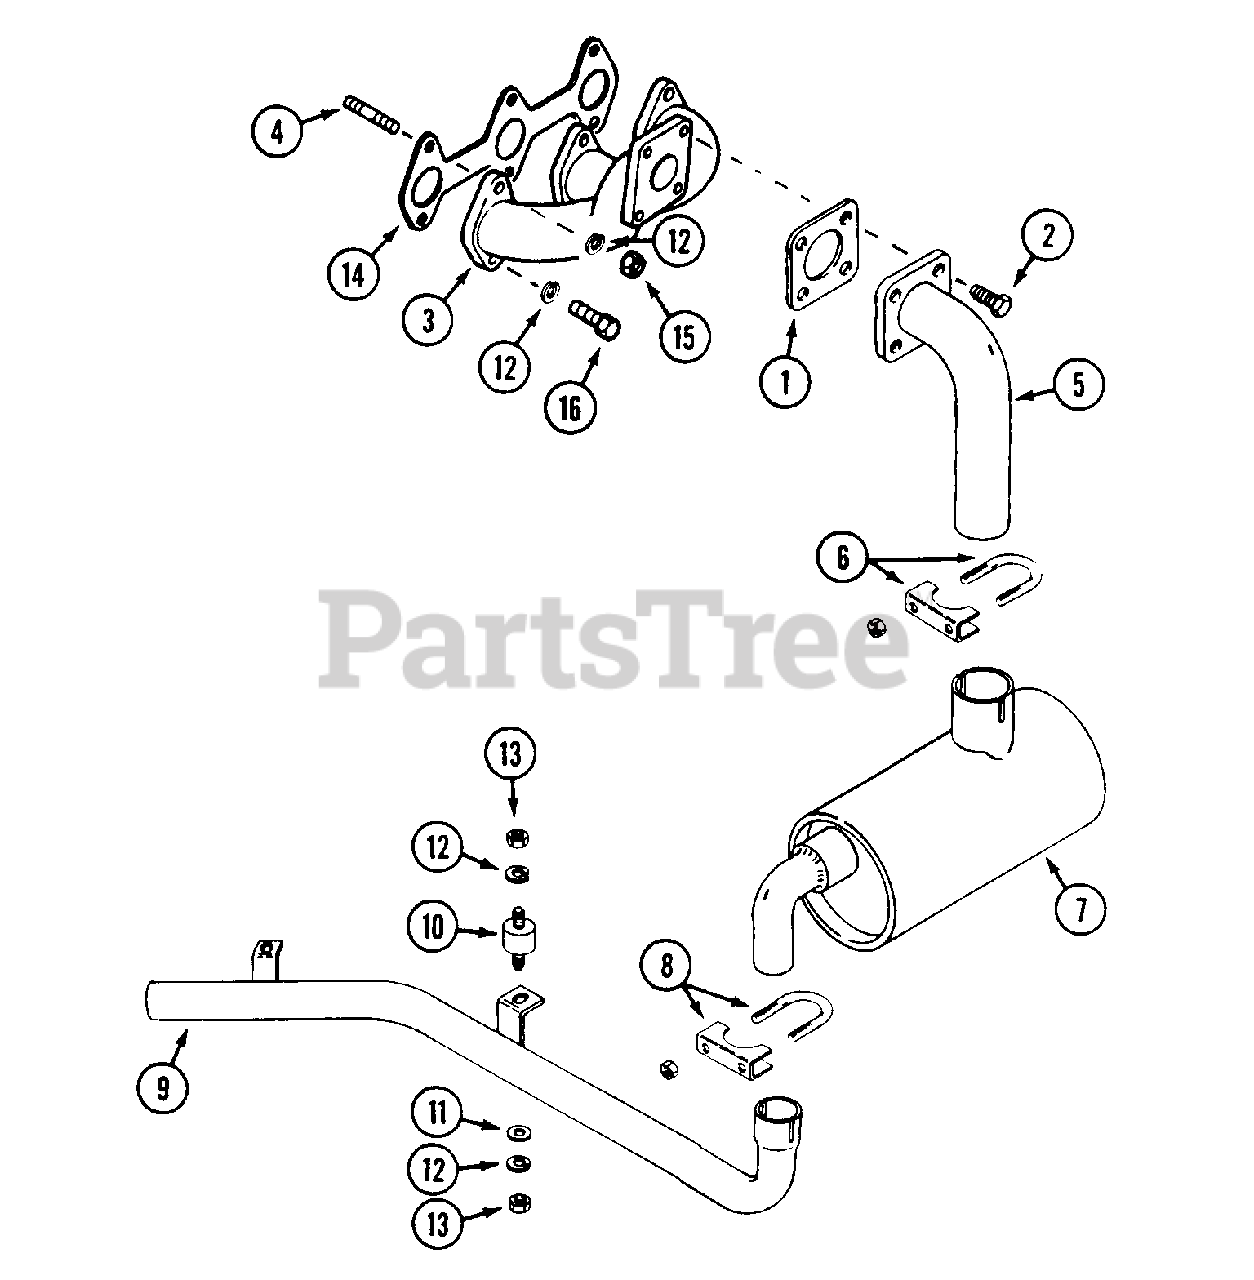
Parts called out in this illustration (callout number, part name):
1	GASKET - exhaust
2	BOLT - M8 - 1.25 x 25
3	MANIFOLD - exhaust
4	STUD - manifold
5	PIPE - engine to muffler
6	CLAMP - muffler 1-3/4"
7	MUFFLER ASSEMBLY
8	CLAMP - muffler 1-3/8"
9	PIPE - exhaust
10	MOUNT - rubber
11	WASHER - 1/4"
12	LOCKWASHER - 1/4"
13	NUT - 1/4" - 20
14	GASKET - manifold
15	NUT - M6 - 1.0
16	BOLT - M6 - 1.0 x 25
